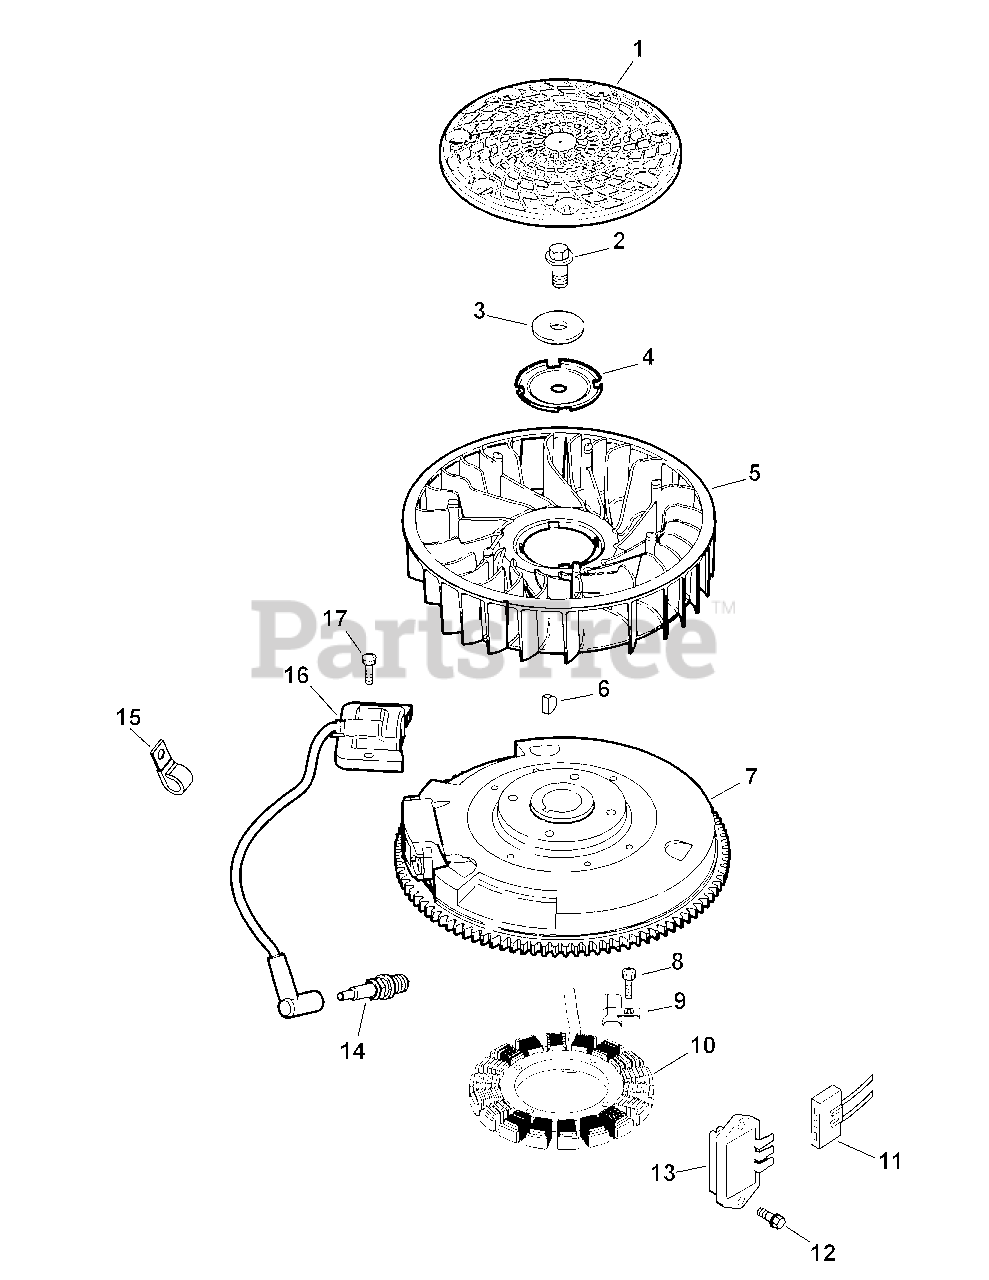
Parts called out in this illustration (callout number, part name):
2	Hex Flange Screw, M10 x 1.5 x 45
3	Flat Washer, 13/32
4	Fan Mounting Plate
6	Woodruff Key
7	Flywheel
8	Hex Socket Screw, M5 x 0.8 x 25
9	Stator Wire Clip
10	Stator Kit
11	Body Connector (3 Contact)
12	Hex Flange Screw, M5 x 0.8 x 20
13	Regulator Rectifier
14	Spark Plug
16	Ignition Module
17	Hex Socket Screw, M5 x 0.8 x 25
